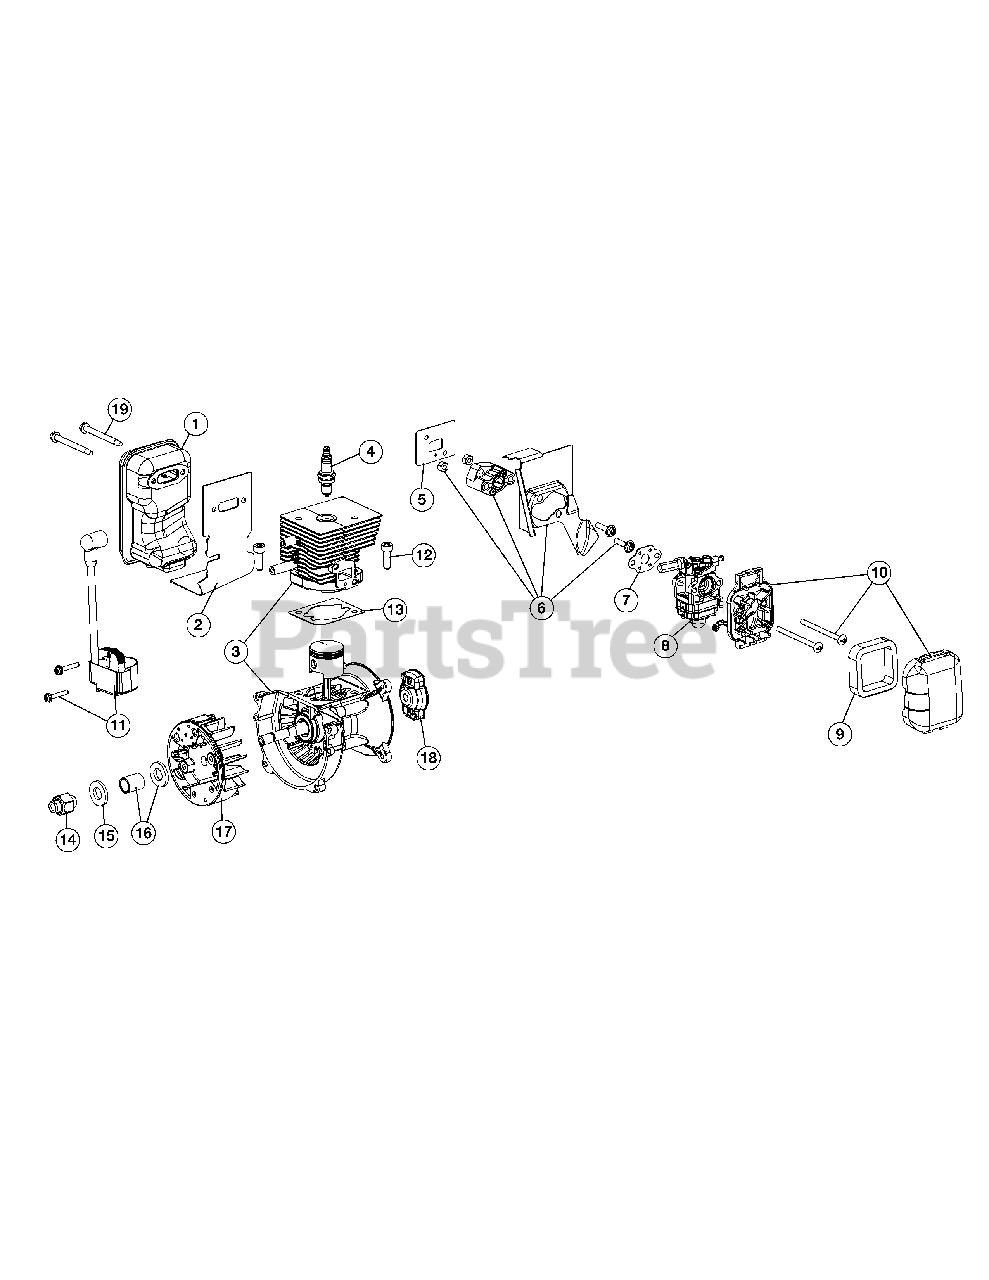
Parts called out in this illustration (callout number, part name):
1	Muffler Assembly (Incl. Ref No. 2 & 19)
2	Muffler Gasket
3	Shortblock Assembly (Incl. Ref No. 4 & 11-17)
4	Spark Plug
5	Insulator Gasket
6	Insulator Assembly (Incl. Ref No. 5)
7	Carburetor Gasket
8	Carburetor Assembly (Incl. Ref No. 7)
10	Air Cleaner Assembly (Incl. Ref No. 9)
11	Module Assembly
13	Cylinder Gasket
14	Flywheel Adapter
15	Washer
17	Flywheel Assembly
18	Pawl Assembly
19	Muffler Screws
